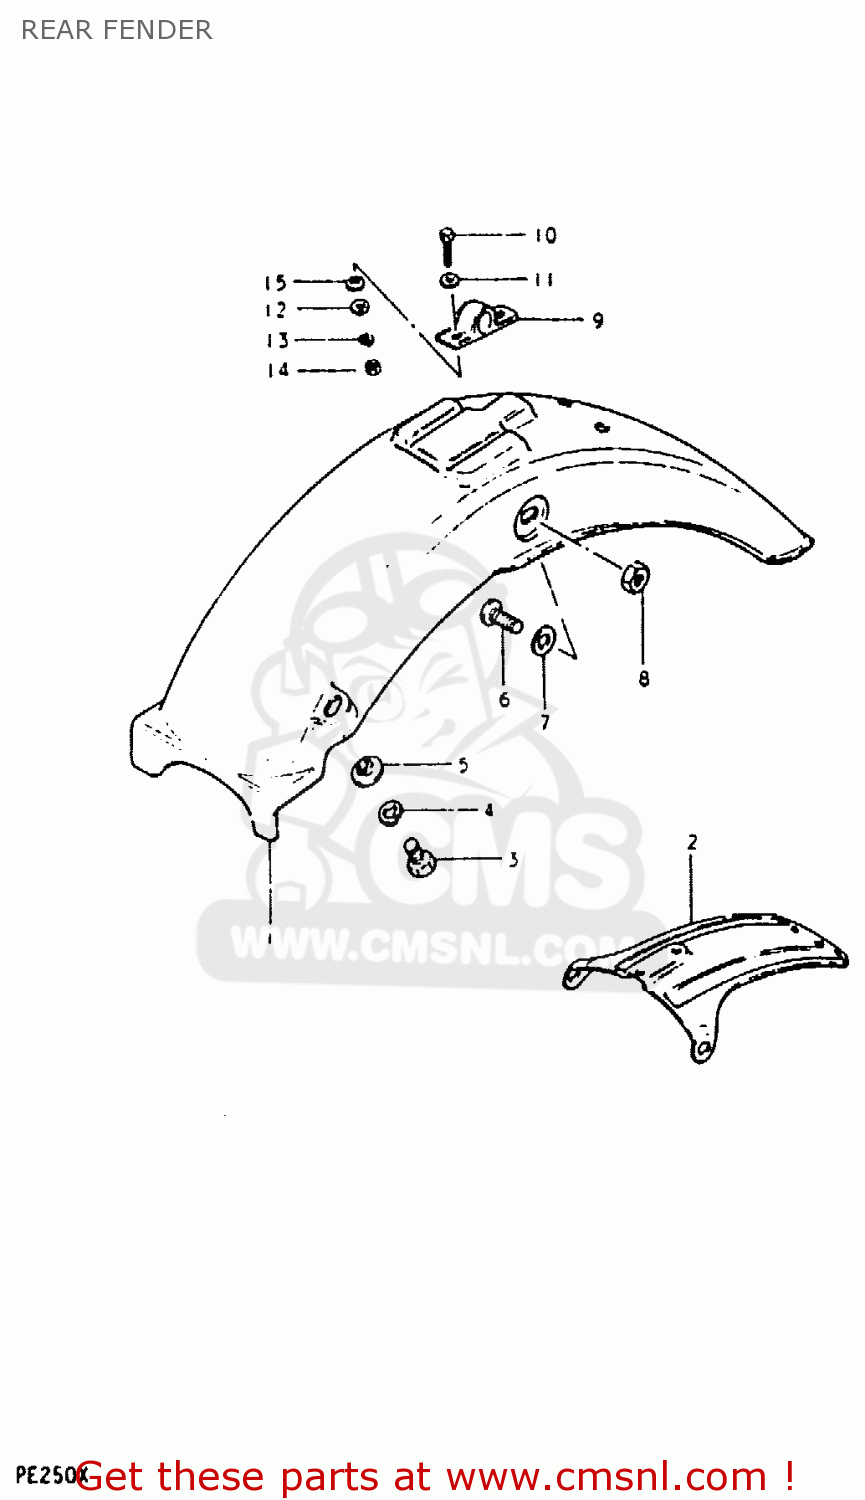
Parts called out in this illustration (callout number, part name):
1	FENDER, REAR (YELLOW)
3	BOLT
4	LOCK WASHER
5	WASHER
6	SCREW
7	WASHER (6.5X20X1.2)
8	NUT 6MM
